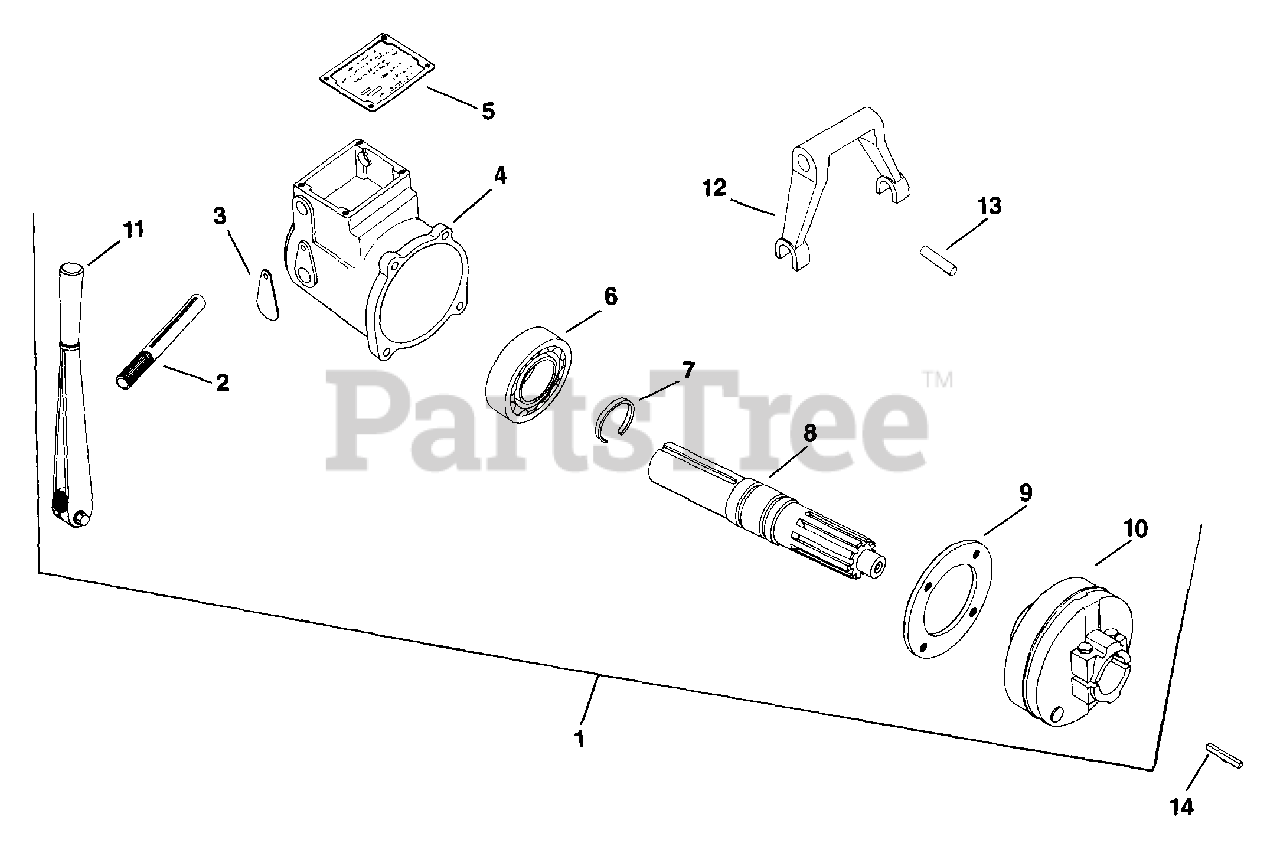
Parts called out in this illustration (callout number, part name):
1	CLUTCH - DISCONTINUED
2	SHAFT - DISCONTINUED
6	BEARING - DISCONTINUED
7	SNAP RING - DISCONTINUED
8	SHAFT - DISCONTINUED
9	PLATE - DISCONTINUED
11	LEVER - DISCONTINUED
12	YOKE - USE 24 471 01
